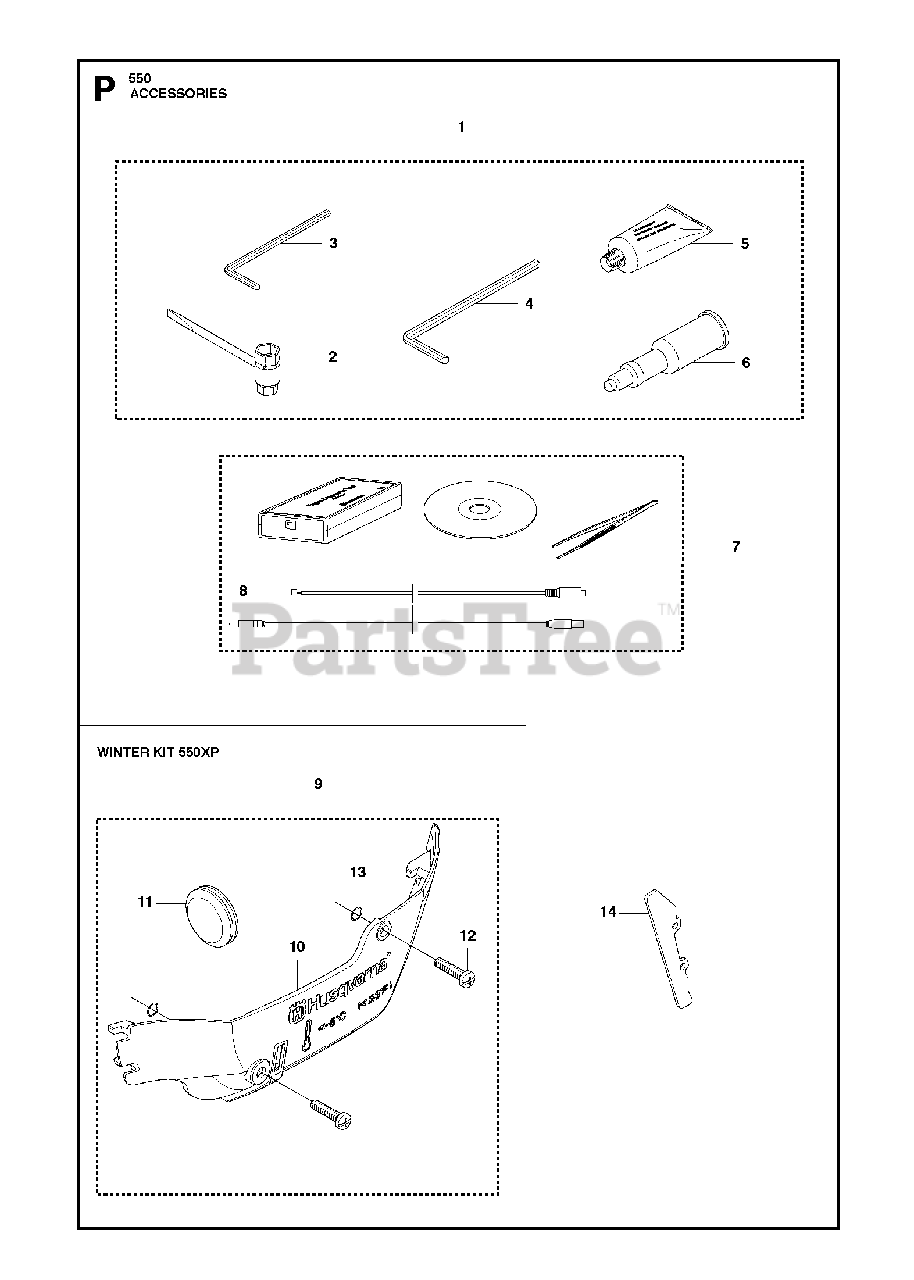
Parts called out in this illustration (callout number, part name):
2	COMBINATION WRENCH
3	L-SPANNER
4	L-SPANNER
5	GREASE
6	Grease Gun
7	SERVICE TOOLS
8	CABLE ASSY
9	WINTER KIT
10	WINTER COVER
11	WINTER PLUG
12	SCREW
13	O-RING
14	BUMPER, BAG
